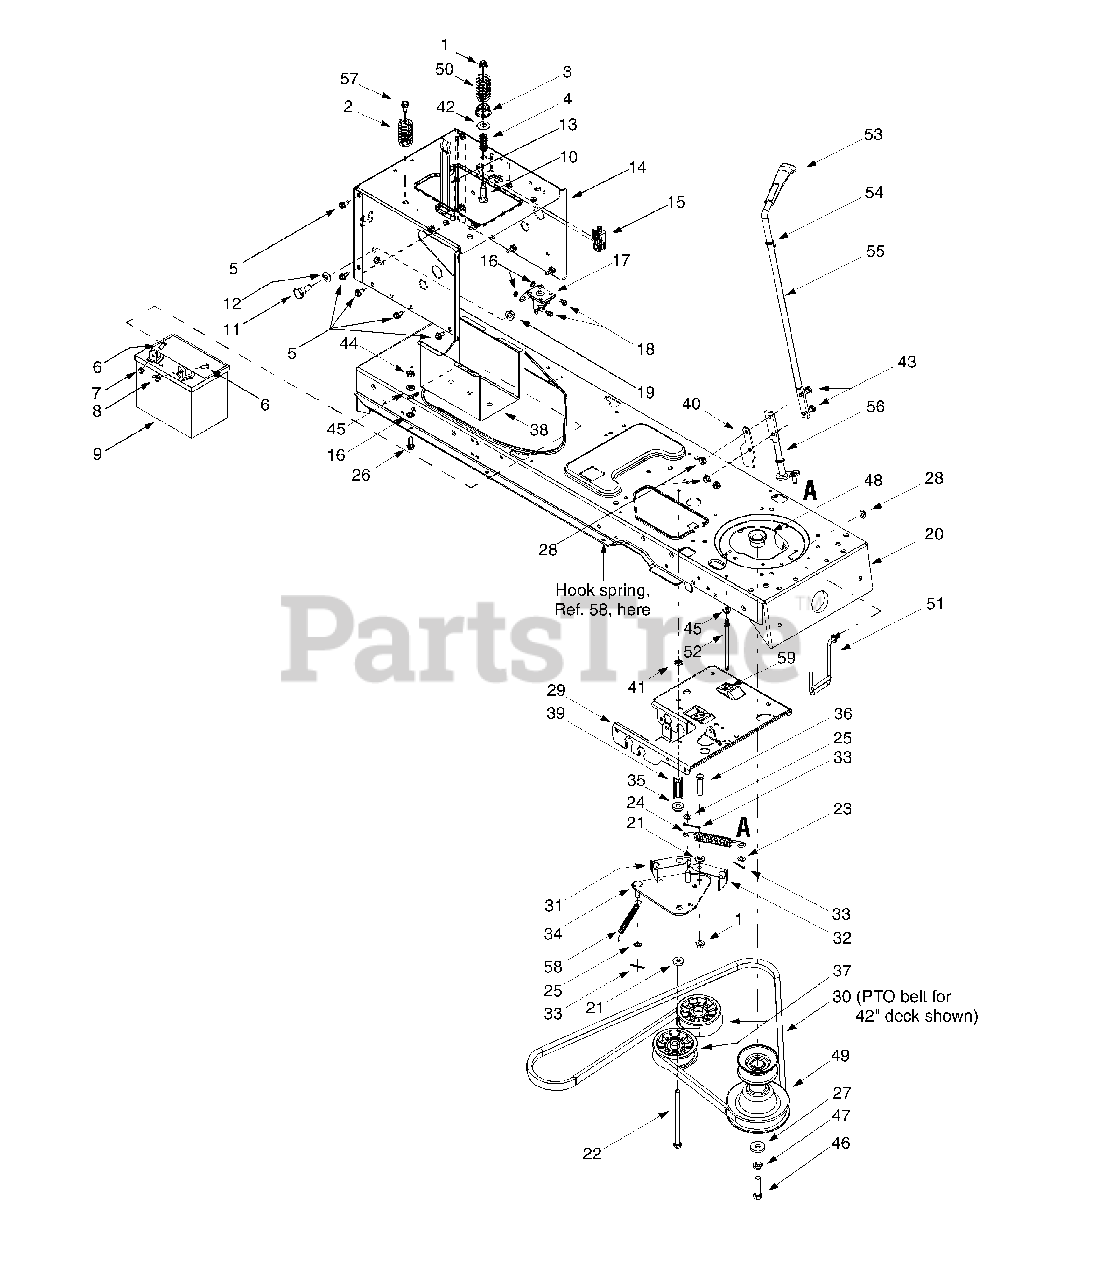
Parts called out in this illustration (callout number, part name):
1	Flange Lock Nut, 3/8-16
2	Compression Spring, 1.31 x 3.0
3	Spacer Cup, 1.5 OD
4	Compression Spring, .66 OD x 1.5
5	Self-tapping Screw, 5/16-18 x .625
6	Hex Cap Screw, 1/4-20 x .62
7	Hex Sems Nut, 1/4-20
8	Wing Nut, 1/4-20
9	12-volt Battery, 270 CCA
10	Shoulder Screw, .5 x 1.25, 3/8-16
11	Shoulder Screw, .625 x .5, 7/16-20
12	Bell Washer, .45 x 1.0 x .062
13	Battery Strap
16	Lock Washer, 1/4
17	Solenoid, 12-Volt, 100 Amp
18	Self-tapping Screw, 1/4-20 x .5
19	Flange Lock Nut, 7/16-20
22	Hex Cap Screw, 3/8-16 x 5.5
23	Flat Washer, .344 x .688 x .065
24	Extension Spring, .75 x 6.75 INCH
25	Flat Washer, .385 x .62 x .063
26	Self-tapping Screw, 1/4-20 x .750
27	Flat Washer, .45 x 1.25 x .164
28	Flange Lock Nut, 5/16-18
30	PTO Belt (42-inch Decks)
30	PTO Belt (46-inch Decks)
31	Belt Guard
32	Belt Guard
33	Cotter Pin, 1/8 x 1.25
35	Shoulder Spacer
36	Hex Cap Screw, 3/8-16 x 2.25 (Grade 5)
37	Flat Idler Pulley, 3.5 OD
41	Push Nut, 3/8
42	Bell Washer, .401 x .870 x .063
43	Hex Cap Screw, 5/16-18 x 1.0
44	Hex Nut, 1/4-20
45	Lock Washer, 5/16
46	Hex Cap Screw, 7/16-20 x 1.25
47	Lock Washer, 7/16
48	Spacer
49	Engine Pulley
50	Extension Spring, 1.318 x 2.37
51	Belt Guard
52	Keeper Pin
53	PTO Knob
54	Flat Washer, .510 x .750 x .033
55	PTO Handle
56	PTO Lever
57	Self-tapping Screw, 15/16-18 x .875
58	Extension Spring, .5 x 6.0
59	Hex Split Flange Bearing
